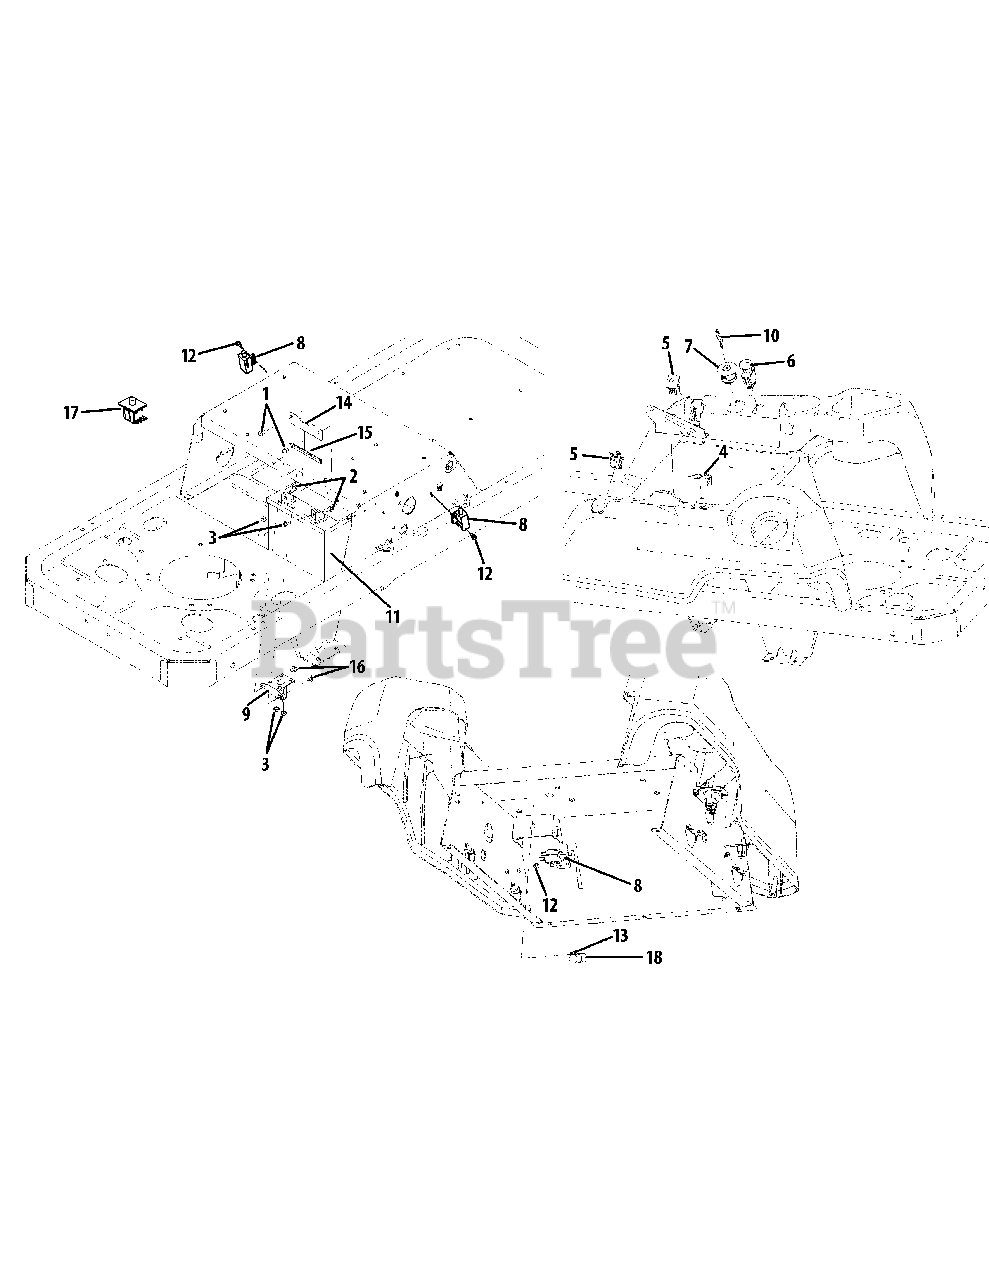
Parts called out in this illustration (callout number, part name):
1	Hex Screw, 1/4-20 x .5
2	Hex Screw, 1/4-20 x .75
3	Hex Nut, 1/4-20
4	Hour Meter
5	Double Pole - Neutral Switch
6	PTO Switch
7	Ignition Switch
8	Interlock Switch
9	Solenoid
11	Battery, 235 CCA
12	Shoulder Screw, #10-32 x .500
13	Cable Tie
14	Battery Hold-down
15	Trim Strip
16	Hex Screw, 1/4-20 x .375
17	Seat Switch
18	Wire Harness
